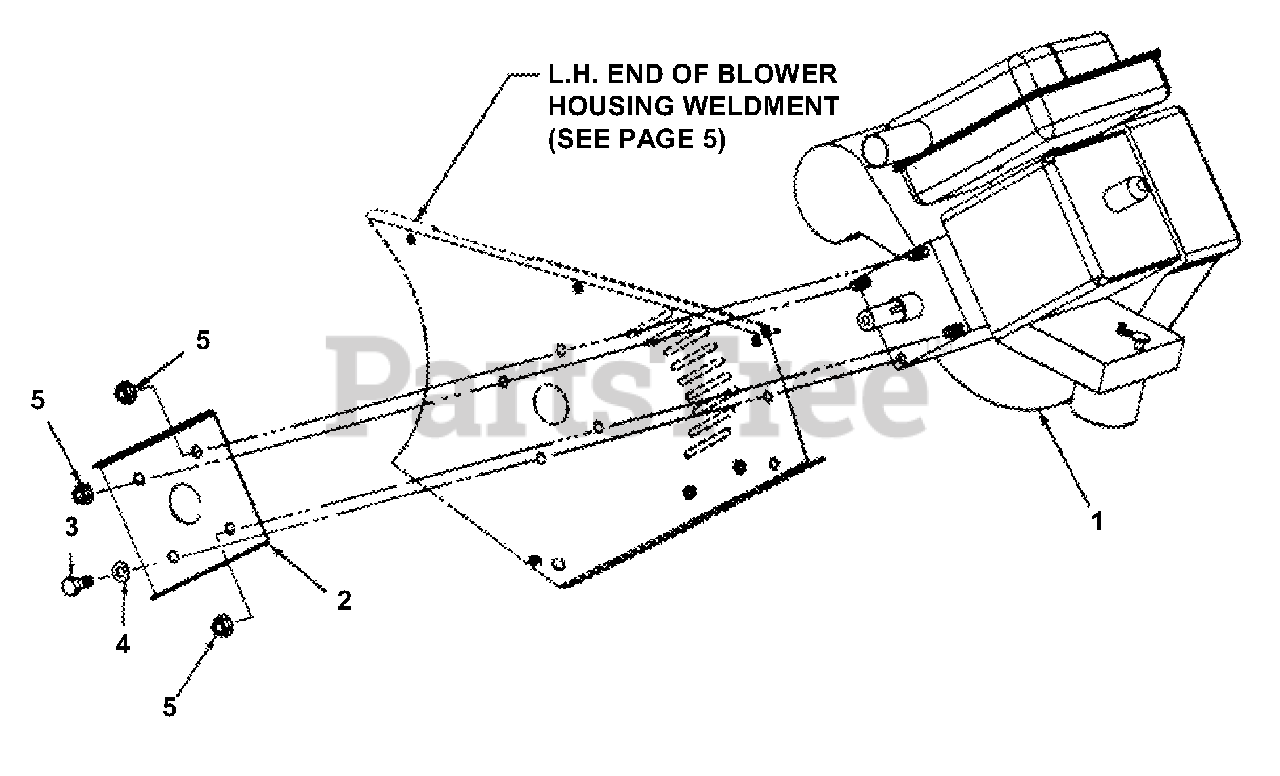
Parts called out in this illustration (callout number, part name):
1	ENGINE, Tecumseh; Model HSK850-8318C, 5HP, 2-Cycle (Electric Start)
2	PLATE, Stiffener
3	SCREW, 5/16-24 x 3/4" Hex Head Cap, Grade 5
4	WASHER, 5/16 Split Lock
5	NUT, 5/16-18 Hex Flange Lock, Grade 5
